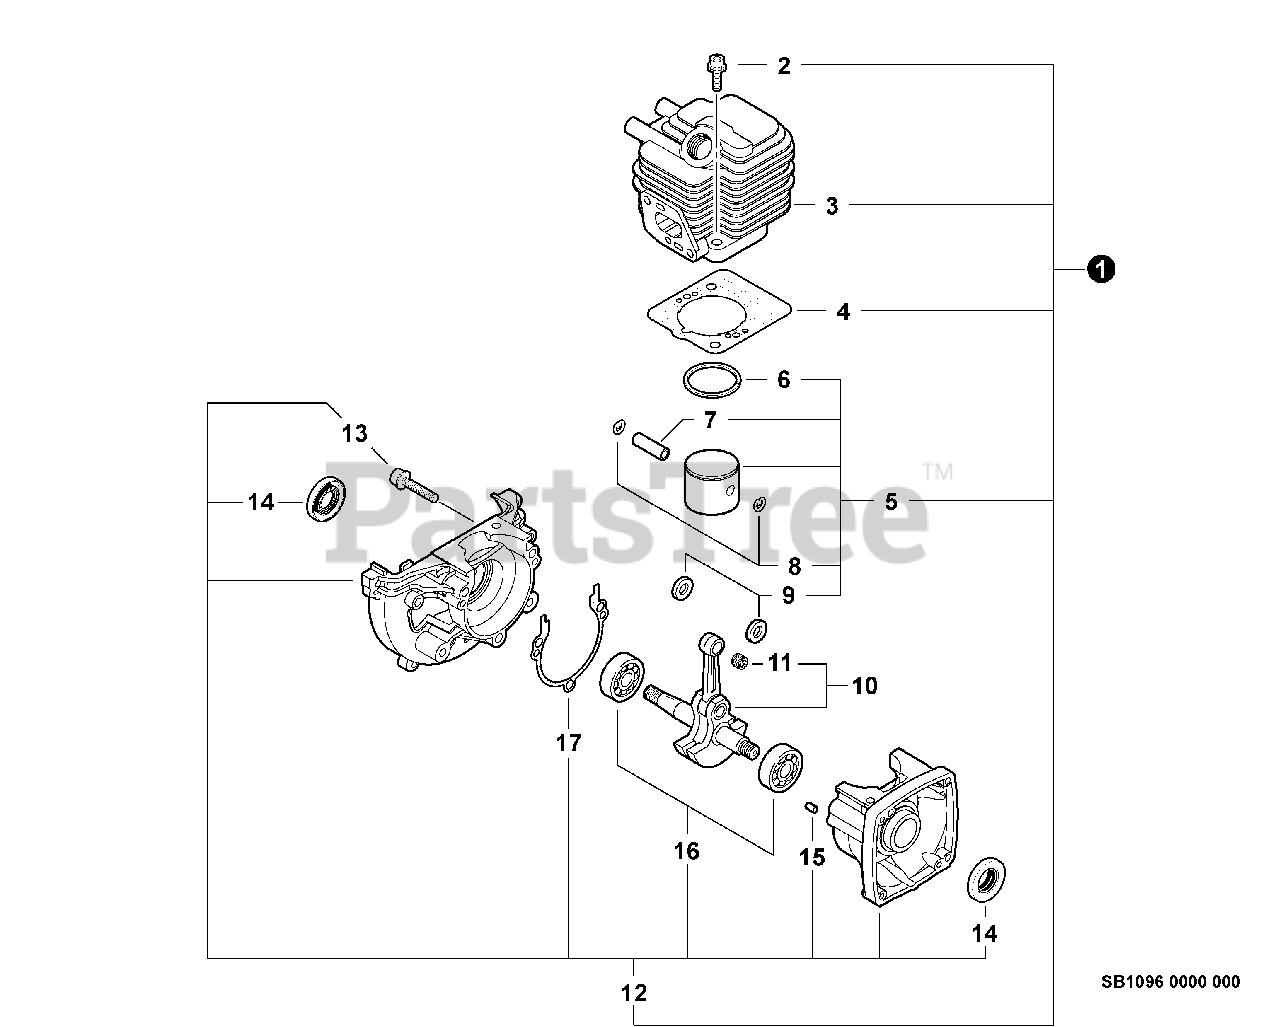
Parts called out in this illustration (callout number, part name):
1	SHORT BLOCK
2	BOLT 5×22
3	CYLINDER
4	GASKET, CYLINDER
5	PISTON KIT
6	RING, PISTON
7	PIN, PISTON 8
8	RING, SNAP
9	WASHER, THRUST
10	CRANKSHAFT ASSY
11	BEARING, NEEDLE 8
12	CRANKCASE KIT
13	BOLT 5×28
14	SEAL, OIL 12
15	PIN, LOCATING 4×8
16	BEARING, BALL - 6201 C3
17	GASKET, CRANKCASE
